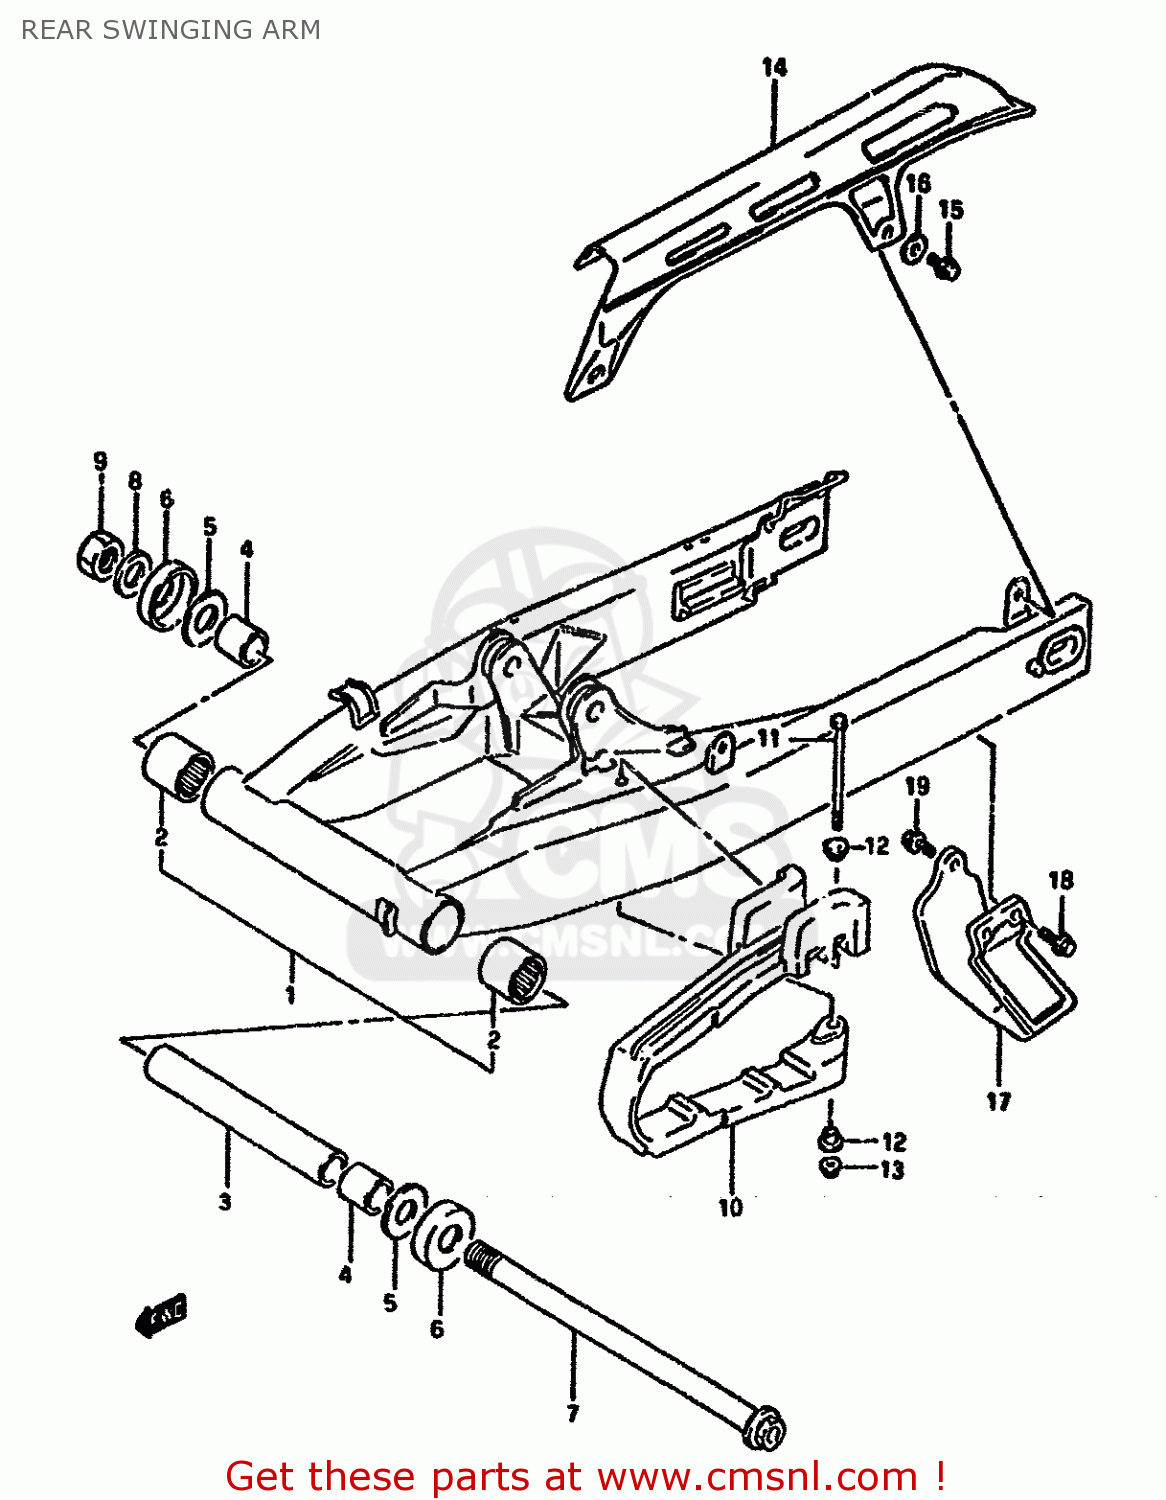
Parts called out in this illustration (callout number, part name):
1	SWING ARM ASSEMBLY,REAR
2	BEARING(22X29X20)
3	SPACER,RR SWGARM PIVOT CTR
4	SPACER,RR SWGARM PIVOT
5	WASHER
6	SEAL,RR SWGARM PIVOT DUST
7	SHAFT,REAR SWING ARM
8	WASHER
9	NUT 16MM
10	BUFFER,CHAIN TOUCH DEFENSE
11	BOLT,TOUCH DEFENSE FTG
12	WASHER
13	NUT
14	CASE,CHAIN
15	BOLT
16	WASHER
17	GUIDE,CHAIN
18	BOLT
19	BOLT
